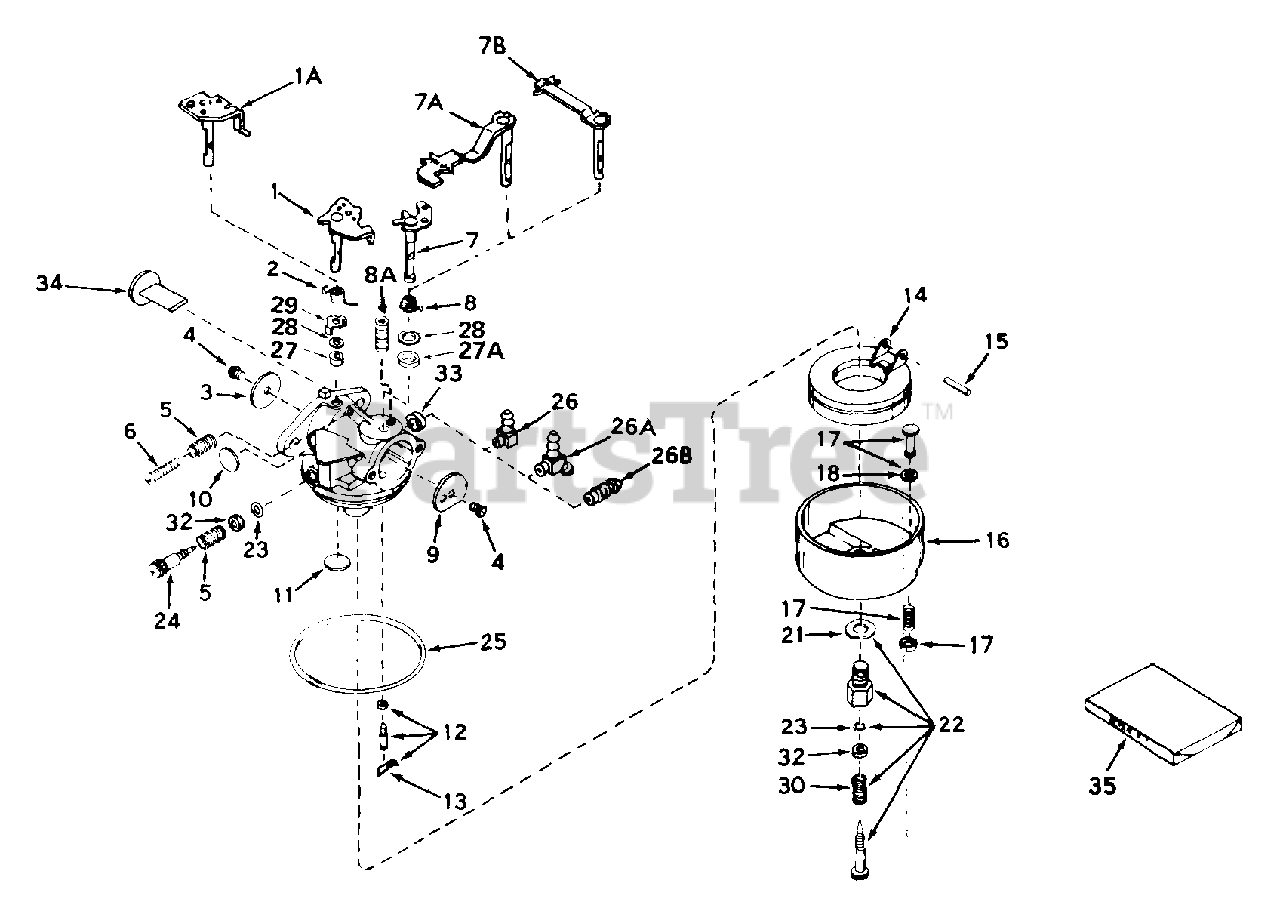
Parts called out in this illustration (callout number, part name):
1	"Shaft & Lever Assy., Throttle
2	Spring, Throttle return
3	Shutter, Throttle
4	Screw, Throttle & Choke shutter
5	Spring, Regulating screw
6	Screw, Idle regulating
7	Shaft & Lever Assy., Choke
8	Spring, Choke return
9	Shutter, Choke
10	Plug, Welch
11	Plug, Welch
12	Inlet Needle, Seat & Clip Assy.
13	Clip, Inlet needle
14	Float, Carburetor
15	Shaft, Float
16	Bowl & Drain Assy., Float
17	Plunger Assy., Drain
18	Gasket, Drain plunger
21	Gasket, Bowl-to-body
22	Adj. Screw Assy., Main
23	"O" Ring, Adj. screw
24	Screw, Idle adj.
25	Gasket, Bowl-to-body
26A	Fitting, Fuel inlet
30	Spring, Main adj. screw
35	Repair Kit
